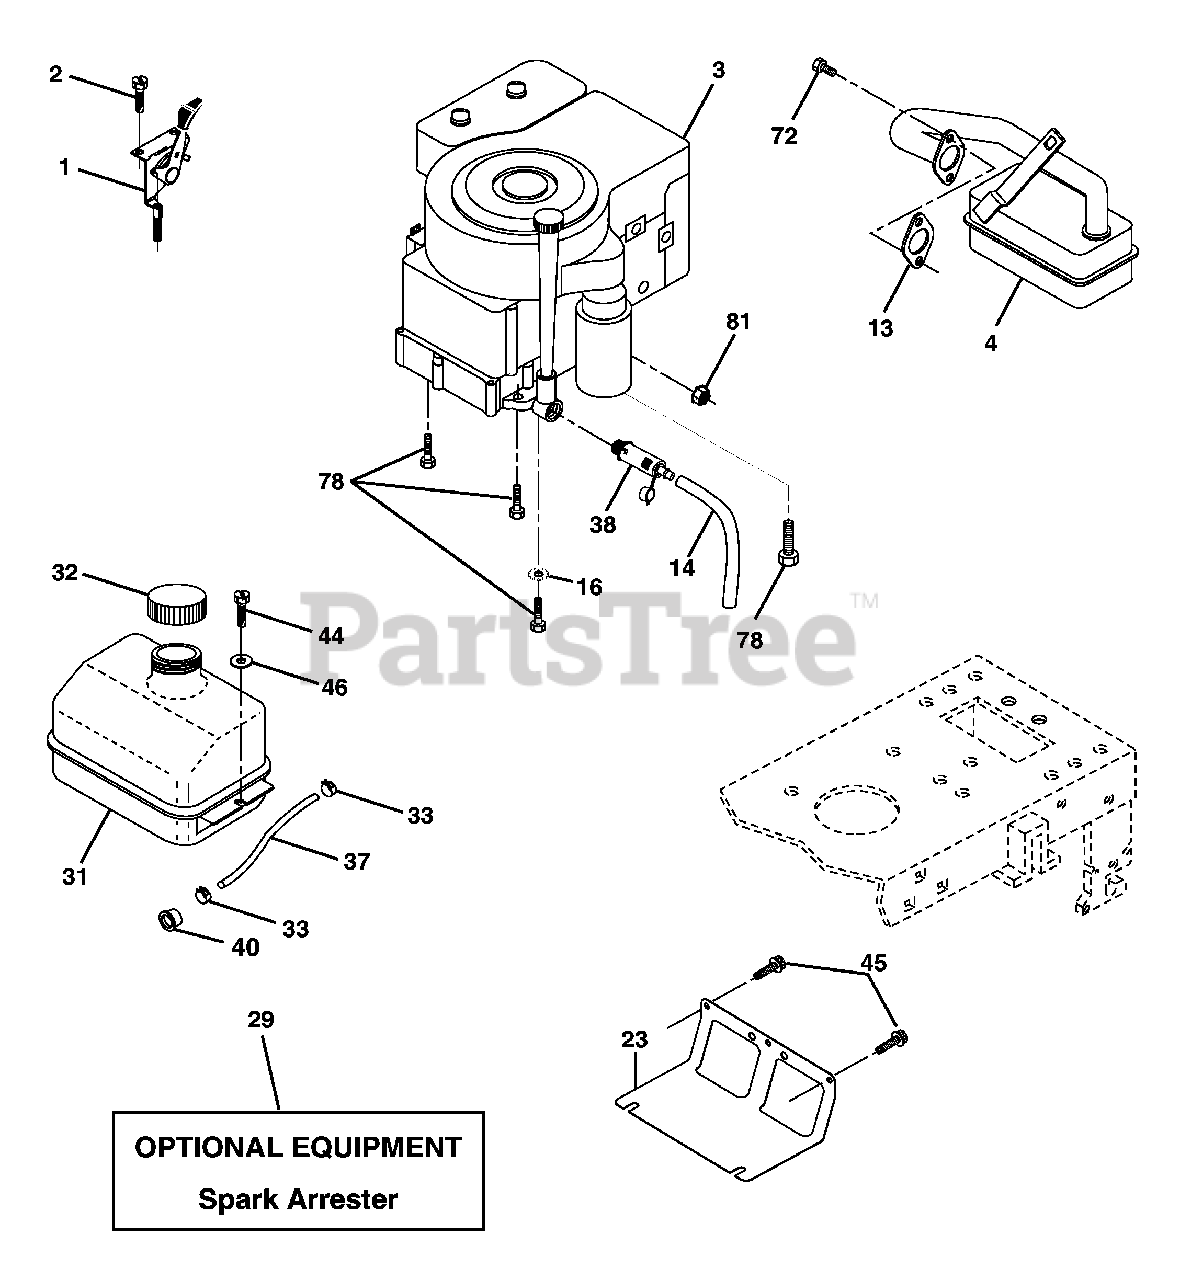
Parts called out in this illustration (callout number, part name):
1	Control Th/ch Flag
2	Screw Hex Thd Cut 1/4-20x5/8 T
4	Muffl er Exhaust B&S Lc
13	Gasket Eng 1 313 Id Tin Plated
14	Nipple Pipe 3/8 Npt X 3"
15	Elbow Std 90 Degree 3/8-18 Npt
16	Washer Lock Ext Tooth 3/8
23	Shield Browning/Debris Guard
29	Kit Spark Arrestor (Flat Scrn)
31	Tank Fuel Front
32	Cap Asm Fuel
33	Clamp Hose
35	Screw Thdrol 5/16-18 x 3/4
37	Line Fuel 20"
38	Oil Drain Plug
40	Bushing Snap Nyl Blk Fuel Line
44	Screw Thdrol 1/4-20 x 3/4
46	Washer 9/32 X 7/8 X 16 Ga
62	Washer Lock Hvy Hlcl Spr
72	Screw Hex Hd Cap 5/16-18 x 3/4
